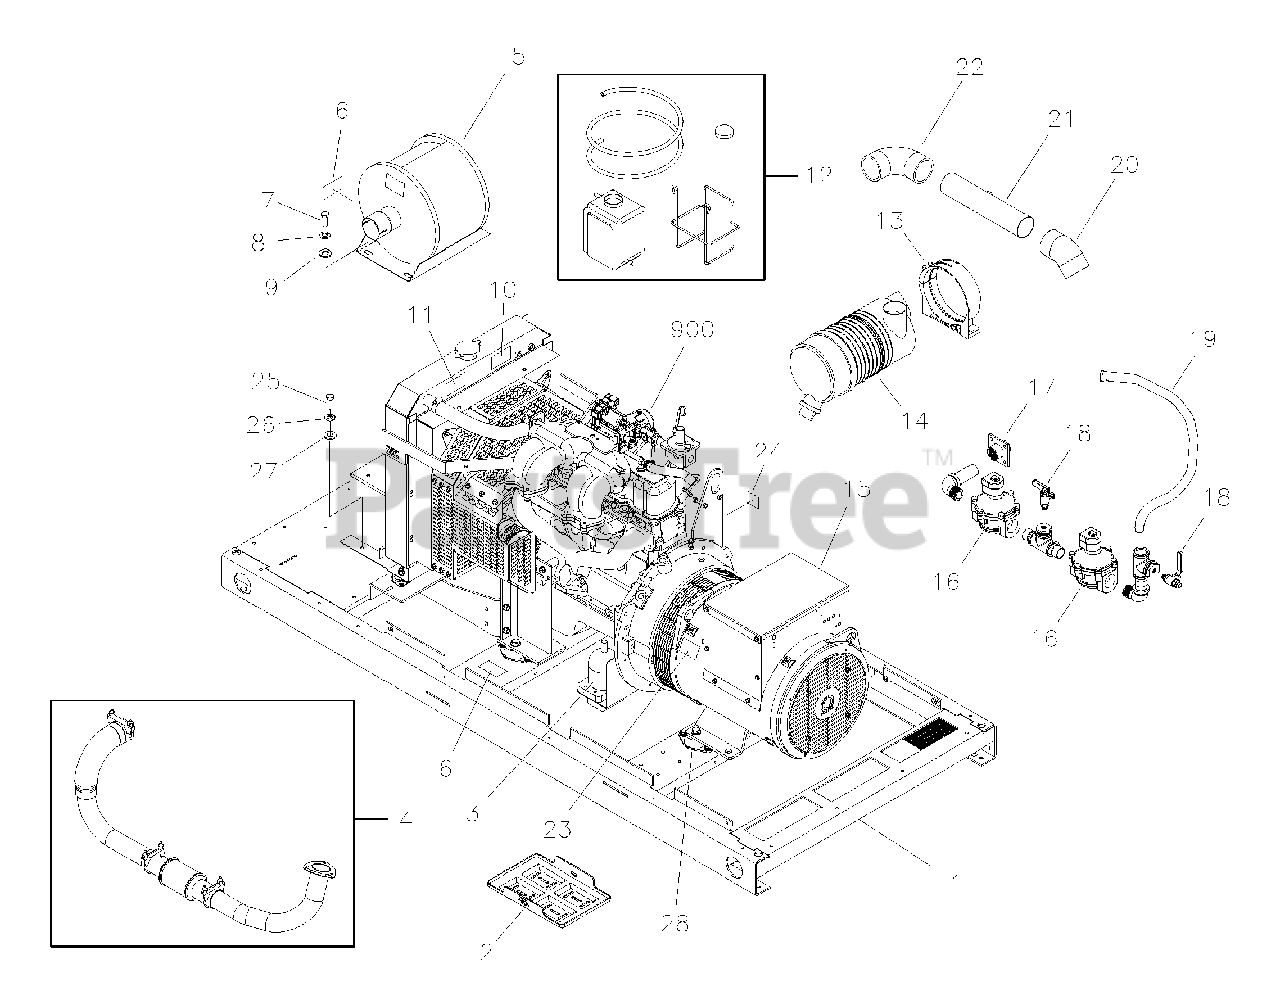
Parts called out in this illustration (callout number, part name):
3	ASSEMBLY, Heater, Tank
5	SILENCER, Muffler
6	DECAL, Burn Hazard
7	* CAPSCREW, Hex Head, 5/16-18 x 3/4
8	* WASHER, Lock, 5/16 - M8
9	* WASHER, Flat, 5/16 - M8
10	DECAL, Warning Hot Coolant
11	DECAL, Warning Moving Parts
12	KIT, Bottle Overflow
13	CLAMP, Air Cleaner
16	ASSEMBLY, Fuel Valve
17	COUPLER, Fuel System
18	VALVE, Ball 1/4
19	ASSEMBLY, Hose, Fuel
21	TUBE, Inlet, Air
23	DECAL, Explosion Hazard
24	DECAL, Oil Drain
25	* CAPSCREW, Hex Head, 1/4-20 x 3/4
26	* WASHER, Lock, 1/4 - M6
27	* WASHER, 1/4
28	MOUNT, Vibration
900	** ENGINE
